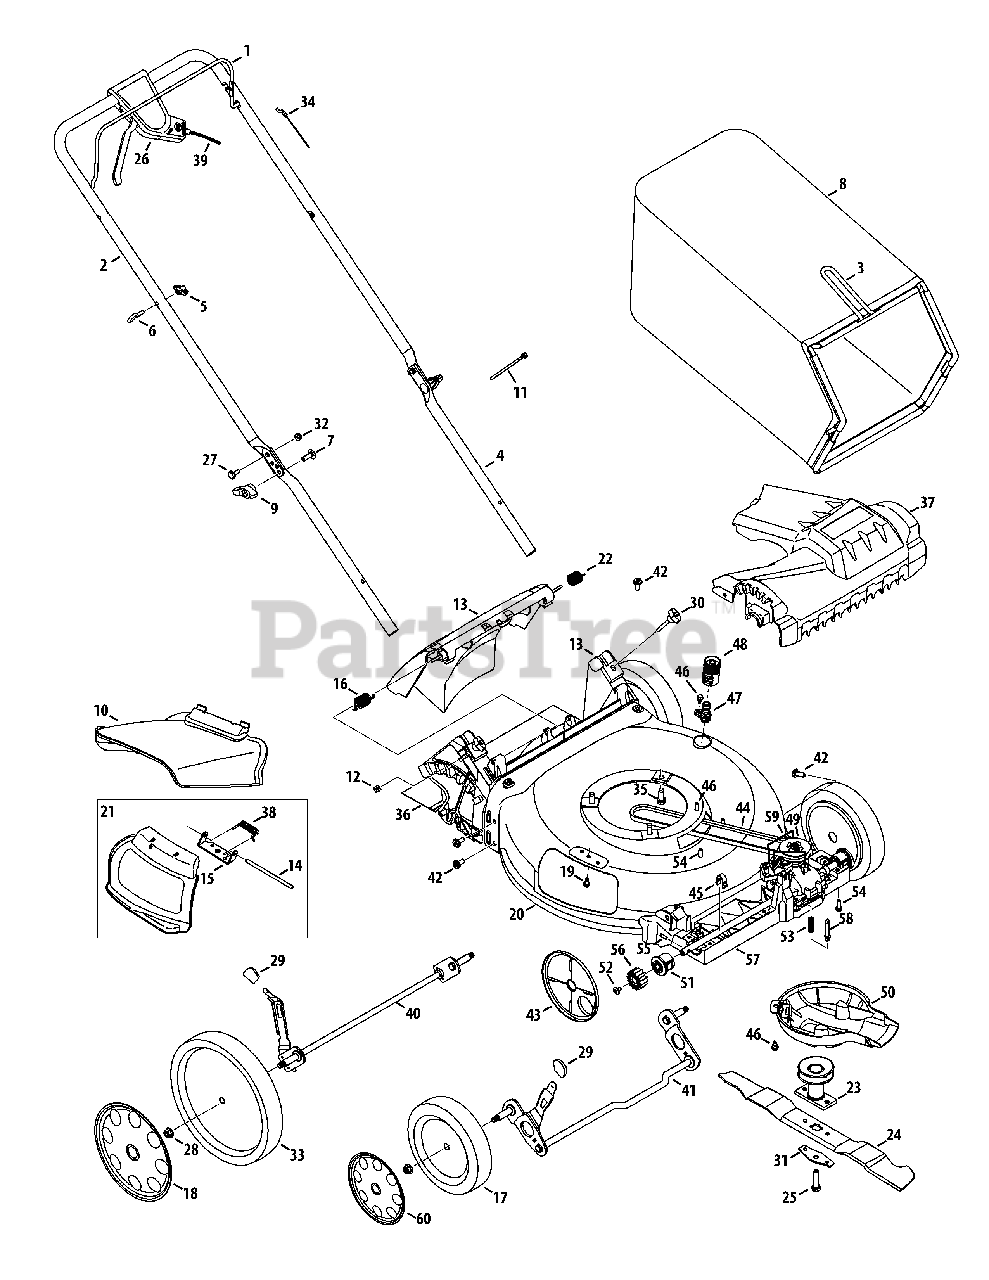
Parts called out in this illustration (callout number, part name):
1	Blade Control
2	Upper Handle
4	Lower Handle
6	Rope Guide
7	Carriage Screw ,5/16-18
8	Grass Bag
10	Side Chute
11	Cable Tie
12	Nut, Sq., 1/4-20
13	Rear Discharge Door Assembly (Lowes Model)
13	Rear Discharge Door Assembly
15	Chute Deflector Bracket
16	Torsion Spring - RH
17	Front Wheel
19	Screw, 1/4-20 x .500
20	Deck , 21"
21	Hinged Mulch Plug Assembly
22	Torsion Spring - LH
23	Blade Adapter Assembly
24	Mulching Blade
25	Screw , 3/8-24 x 1.50
26	Control Lever Assembly
27	Sldr. Screw, .375 x .126 x 1/4-20
28	Flange Lock Nut, 3/8-16
29	Adjustment Lever Knob
30	Wing Nut
31	Blade Bell Support
32	Nut, Flange Lock, 1/4-20
33	Rear Wheel
34	Control Cable
35	TT Sems Screw, 3/8-16 x 1.0
36	Trail Shield
37	Front Cover
38	Torsion Spring
39	Variable Speed Cable
40	Rear Axle Assembly
41	Front Axle Assembly
42	Screw, 5/16-14 x .750
43	Wheel Dust Cover
45	Front Axle Clip
46	Screw, Shldr., 1/4-20 x .50
47	Water Nozzle
48	Water Nozzle Adapter
49	Transmission Assembly
50	Engine Baffle
51	Bearing Assembly
52	Screw, 1/4-20 x .390
53	Compression Spring
54	Screw, 1/4-15 x .750
56	Spur Gear, 14T - RH
56	Spur Gear, 14T - LH
57	Lower Tray
58	Spring Body
59	Transmission Wire
60	Hubcap, 8"
